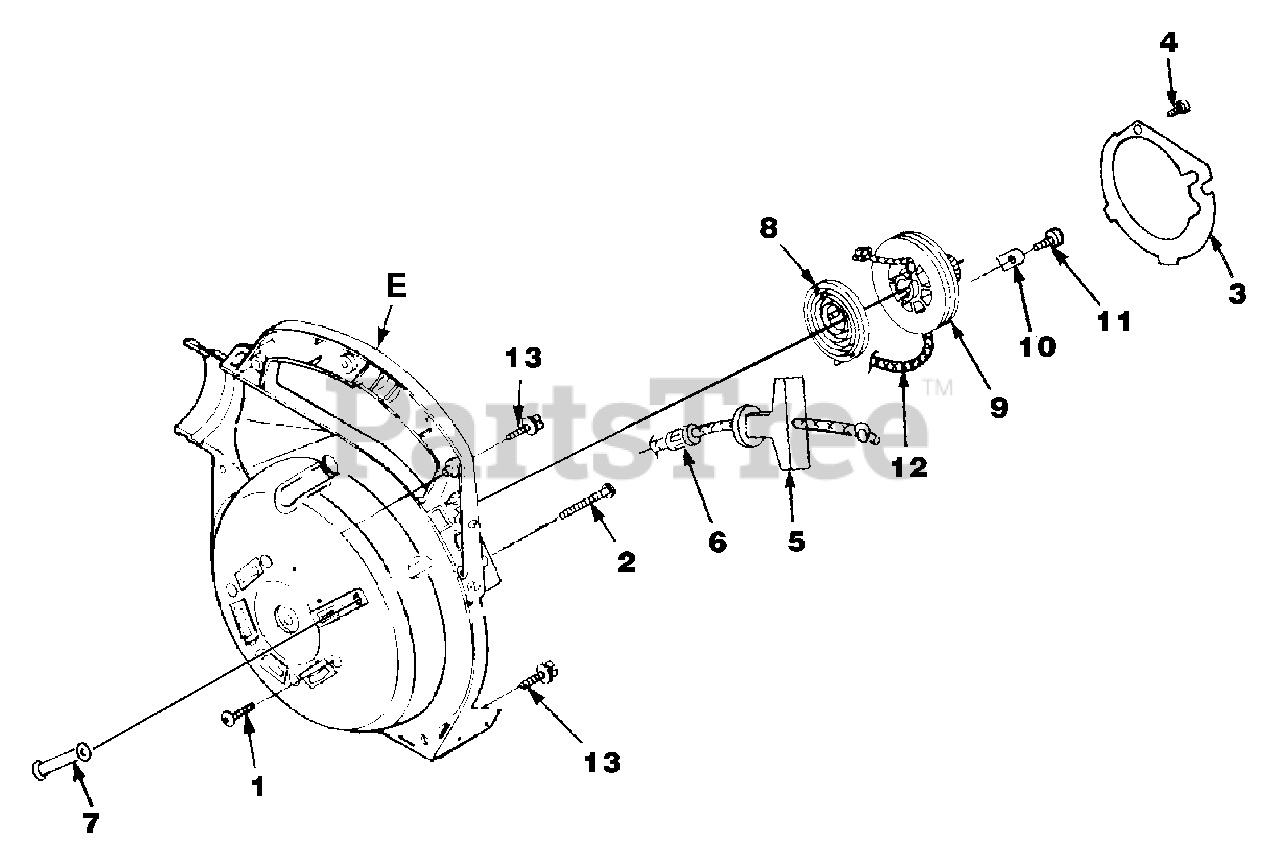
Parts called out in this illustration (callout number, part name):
1	SCREW-Thread Form. (10-24 X 3/4")
2	SCREW-Thread Form. (#10 X 1 5/8")
3	PLATE-Rotor
4	SCREW-Thread Form. (#6 X 1 3/8")
5	GRIP-Starter
6	BUSHING-Starter
7	BUSHING-Starter Rope
8	SPRING & CONTAINER
9	PULLEY-Starter
10	BRACKET-Retaining
11	SCREW-Thread Form. (#10 X 1/2")
12	ROPE-Starter
13	SCREW-Thread Form. (10-24 X 3/4")
E	VOLUTE HOUSING & STARTER
